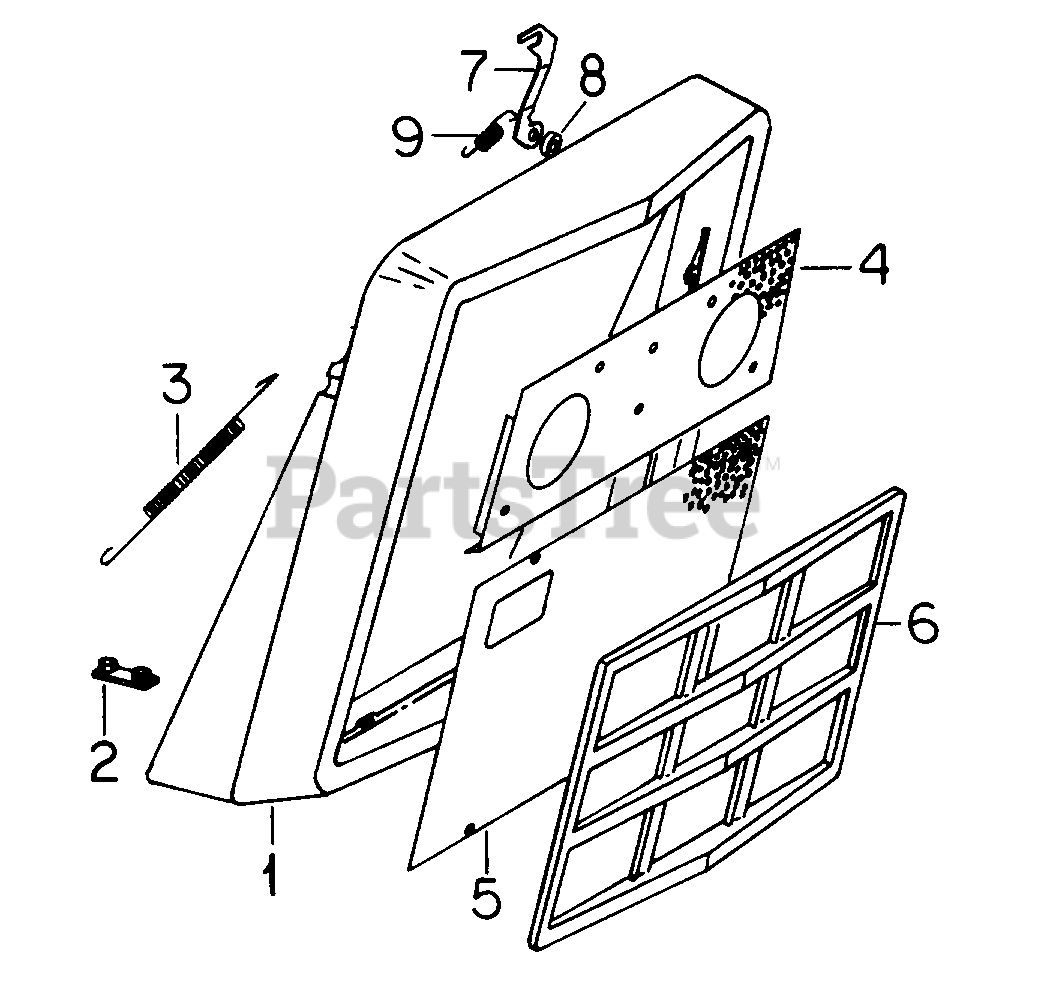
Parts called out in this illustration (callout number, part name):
1	Housing, Grille
2	Retainer Assy, Grille Housing
3	Spring
7	Latch, Hood
8	Spacer, Hood Latch
9	Spring
